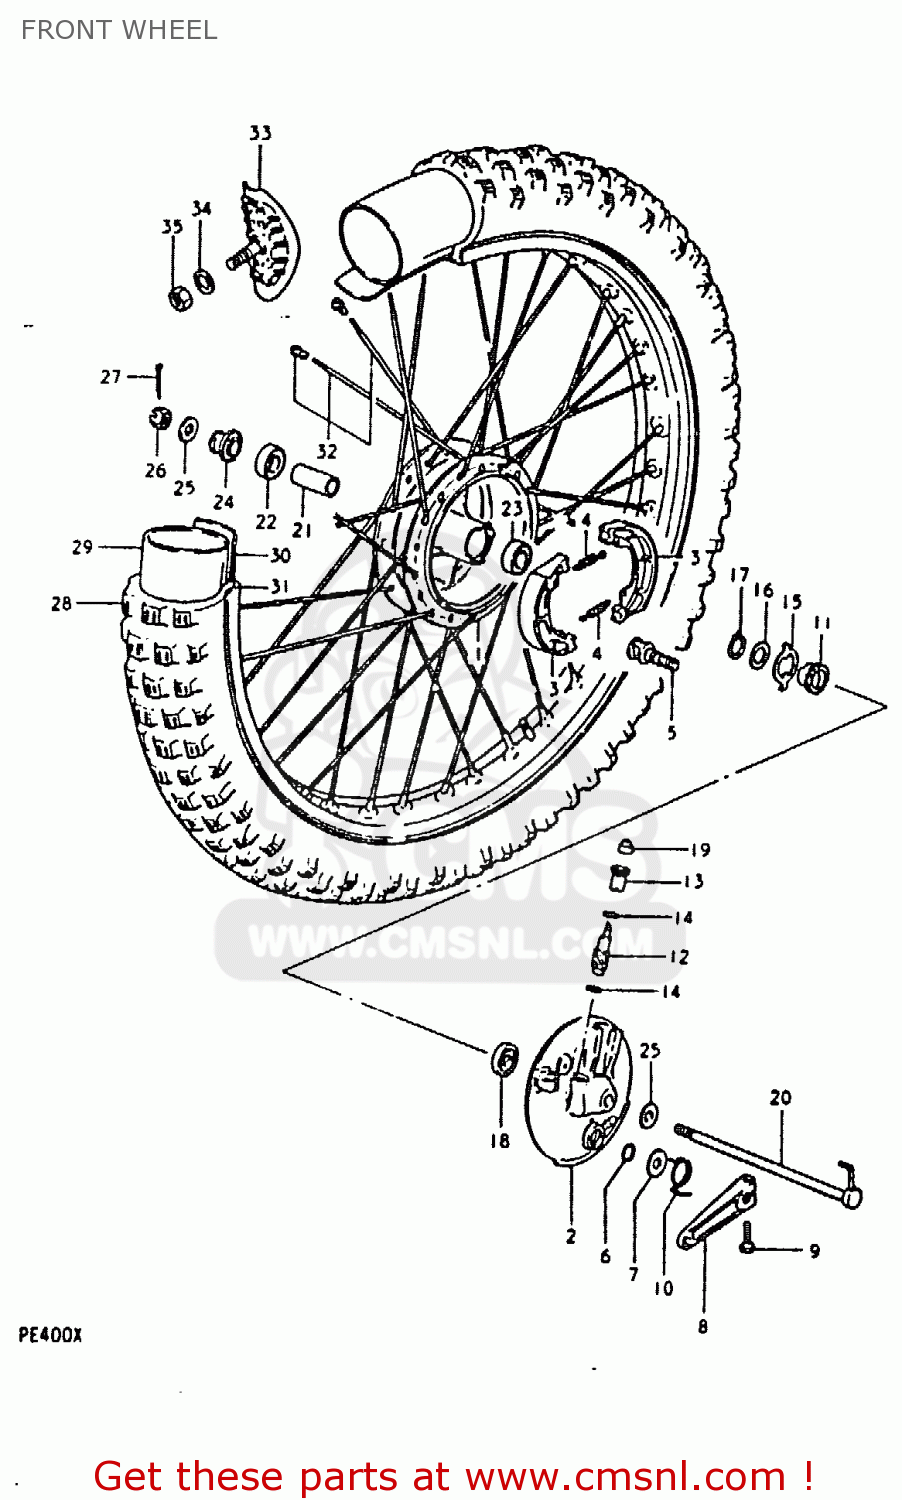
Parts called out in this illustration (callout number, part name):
1	DRUM,FRONT HUB
2	PANEL,FRONT HUB
3	SHOE,BRAKE
4	SPRING
5	CAM,FRONT BRAKE
6	O-RING,BOSS
7	WASHER (15X24X1.6)
8	LEVER,FRONT BRAKE CAM
9	BOLT
10	SPRING
11	GEAR,SPEEDOMETER
12	PINION,SPEEDOMETER
13	BUSHING,SPEEDOMETER PINION
14	WASHER (5.1X9X0.4)
15	DRIVER,SPEEDOMETER GEAR
16	WASHER(22.5X27X1)
17	CIRCLIP
18	SEAL,OIL(26X38X4)
19	SEAL,OIL(6X10X3)
20	AXLE,FRONT
21	SPACER (12.6X19X52)
22	BEARING, RH
23	BEARING
24	SPACER,FRONT AXLE,RIGHT
25	WASHER
26	NUT, REAR AXLE
27	COTTER PIN
28	TIRE,FRONT
29	TUBE,INNER
30	PROTECTOR,WHEEL,INNER
31	RIM,FRONT WHEEL
32	SPOKE SET,FRONT
33	STOPPER,BEAD
34	WASHER
35	NUT
